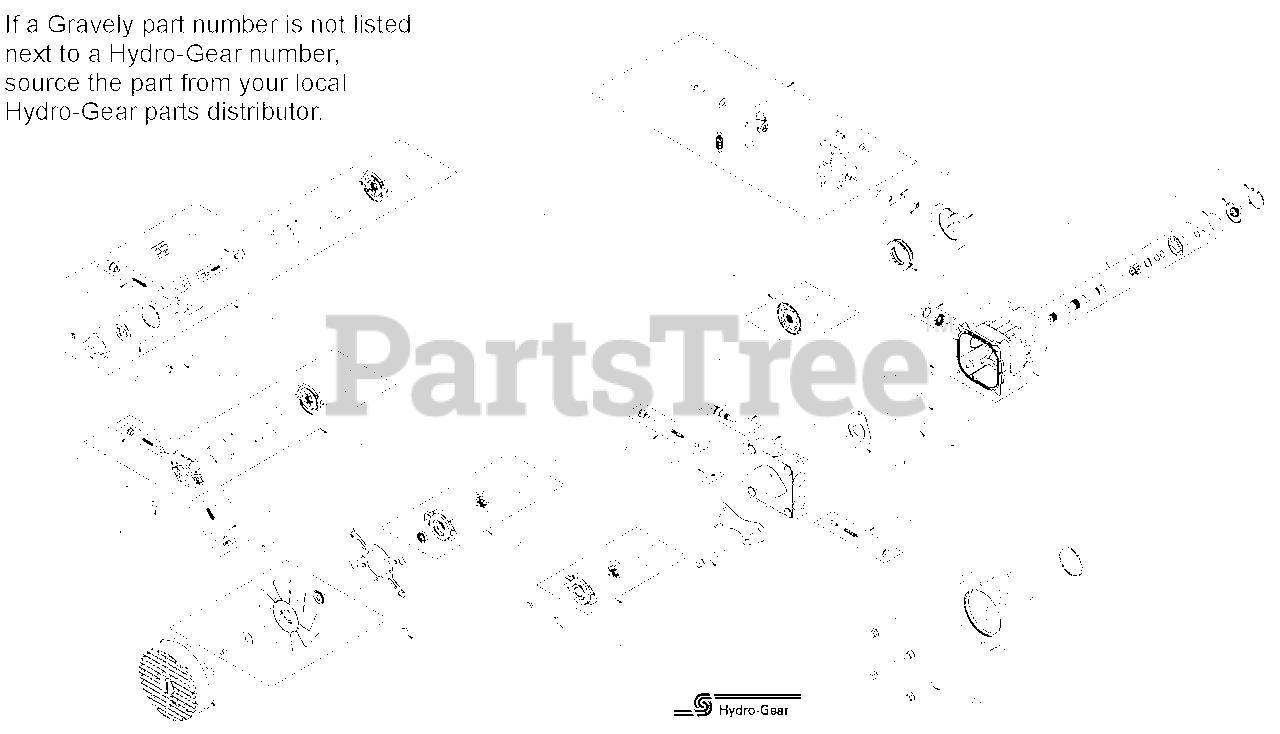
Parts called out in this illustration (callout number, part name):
1	Kit, Input Shaft
3	Ring, Retaining
4	Washer, 1.45 x 1.84 x .04
6	Lip Seal, 17 x 47 x 8
12	Kit, Trunnion Seal
13	Trunnion Arm, Taper Square
14	Slot Guide
15	Kit, Housing
17	Assembly, Thrust Ball Bearing
25	Kit, Encap
26	Pin
28	O-Ring
29	Valve Plate
31	Variable Swashplate
38	Kit, Cylinder Block
42	Kit, Shock Valve
44	Kit, Charge Relief
45	Kit, Auxilary Relief Valve
50	Kit, Bypass Valve
54	Kit, Auxilary Filter Kit
56	Screw, 5/16-18 x 1
58	Kit, HSG Bolt
